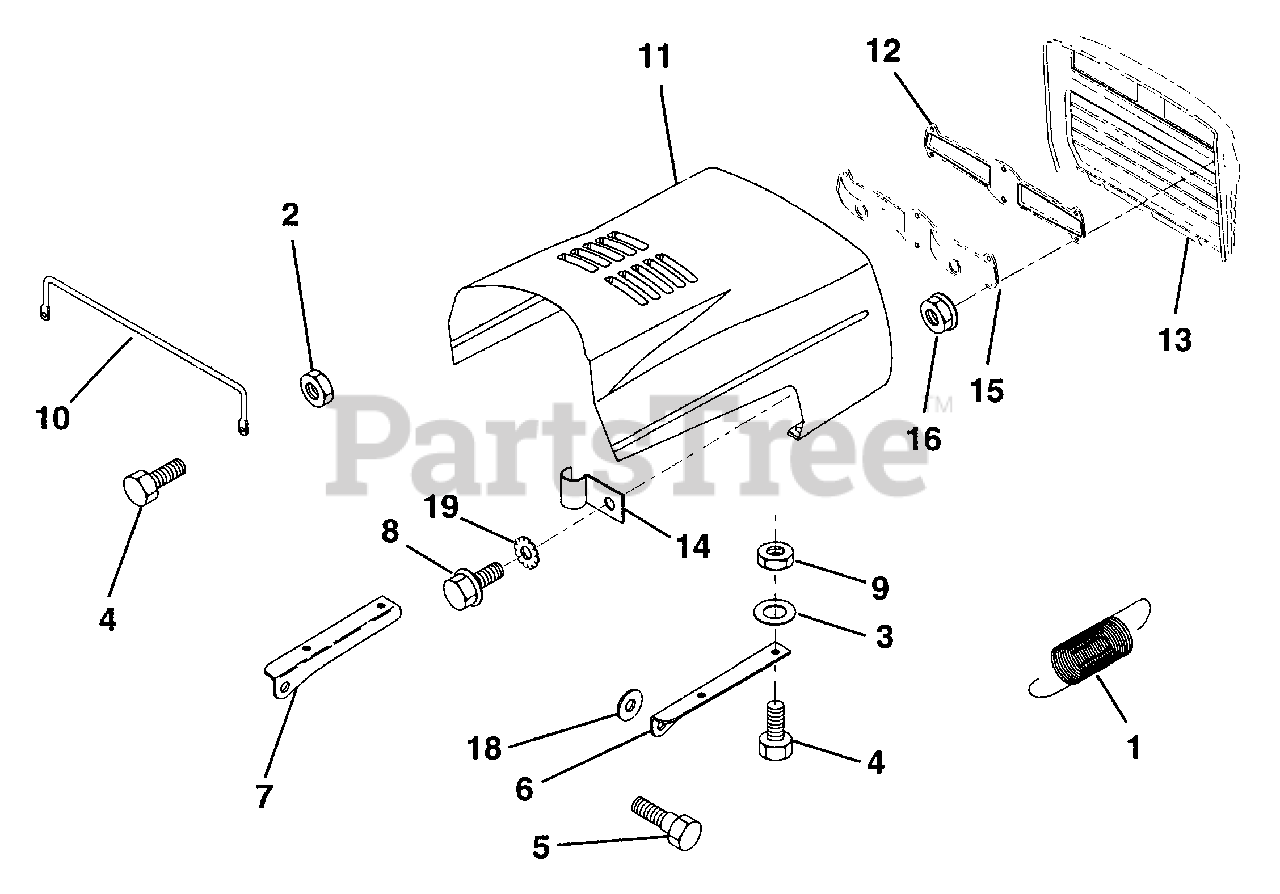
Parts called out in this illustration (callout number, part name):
1	Extension, Spring
2	Nut, Hex, Keps 1/4-20
3	Washer, 9/32 x 7/8 x 16 Ga.
4	Bolt, Hex Fin 1/4-20 x 3/4 Gr. 5
5	Bolt, Shoulder
6	Bracket, Hood R. H.
7	Bracket, Hood L.H.
8	Screw Sltd. Hex Hd W/PL Washer
9	Nut Lock W/Insert 1/4-20 UNC
10	Brace, Hood
11	Hood
12	Lens Clear Bar Dual LR P/L
14	Clip Line Fuel
15	Lightbox (Bezel)
16	Nut Self-Thd. Wsh-Hd 1/4
18	Washer 11/32 x 11/16 x 16 Ga.
19	Washer Lock 1/4 Int/Ext Tooth
